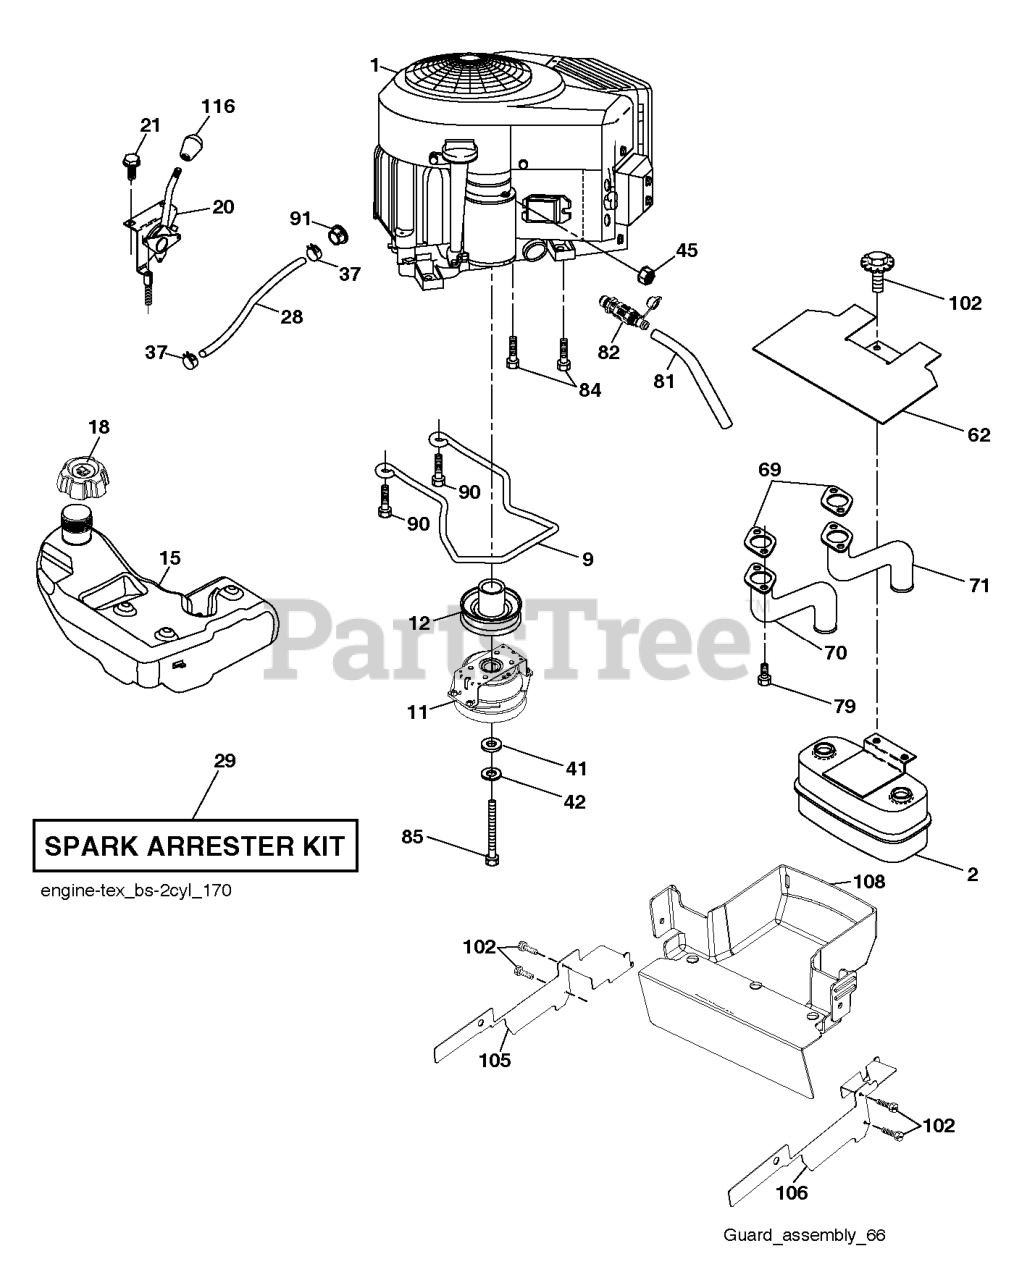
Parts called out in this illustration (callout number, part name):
2	MUFFLER.ASM.TWN.EXTNDED.DFLCTR
9	KEEPER.BELT.ENG.4.25"2.BLT.431
11	CLUTCH.OGURA.5.0PD.GT1.5A-EH01
12	PULLEY ENGINE
15	TANK ASSY 4 GAL FUEL TANK ASM
18	CAP ASSY FUEL 3" GRAY
20	CONTROL.THROTTLE.PRO.
21	SCREW.#10 X 0.750.BOS
28	HOSE 1/4" LOW PERMEATION FUEL
29	KIT.SPARK ARRESTOR 794945 B&S
37	HOSE CLAMP
42	WASHER 7/16 LOCK
45	NUT
62	SHIELD.HEAT.MUFFLER
69	GASKET.MUFFLER
70	EXHAUST.TUBE.LH.BS/TWIN
71	EXHAUST.TUBE.RH.B&S.TWIN.INTEK
79	SCREW.SOCKET.HEAD.5/16-18
81	TUBE, DRAIN OIL ASM.
82	VALUE.OIL.DRAIN
84	SCREW.3/8-16
85	BOLT.HEX.7/16-20X3.GR5.YELLOW
90	SCREW 3/8-16X1
91	BUSHING.1.375OD
102	SCREW
105	SHIELD 48 CLEARCUT EURO TRACTO
106	SHIELD 48 CLEARCUT EURO TRACTO
108	COVER 48 CLEARCUT EURO TRACTOR
116	KNOB - SHIFT
